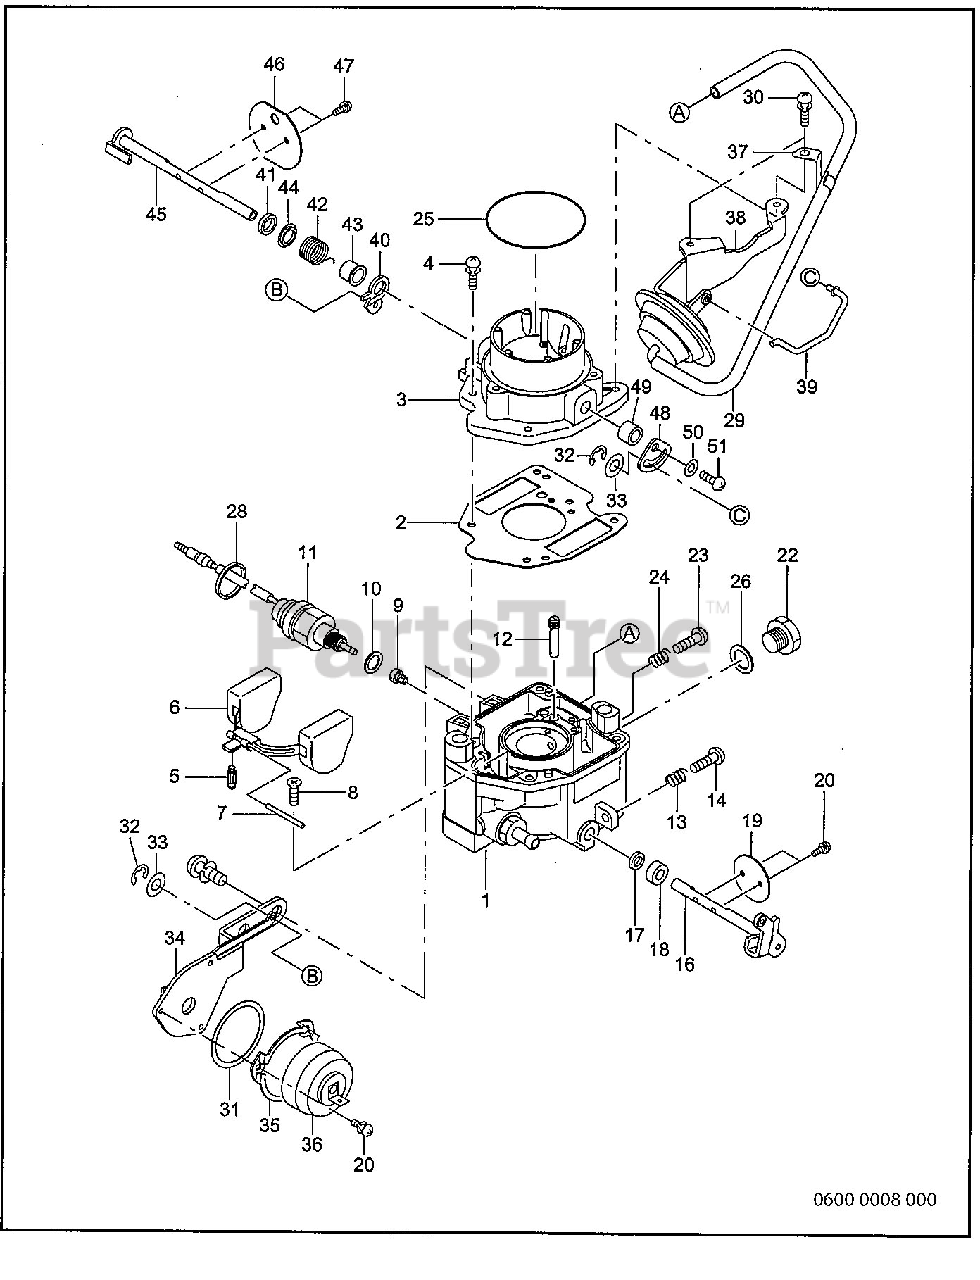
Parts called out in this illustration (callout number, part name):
1	CARBURETOR ASSY
2	GASKET, air horn
4	SCREW, air horn set
8	SCREW, float pin set
9	MAIN JET (#132)
11	SOLENOID VALVE ASSY
12	JET, slow (#60)
13	SPRING, adjust screw
14	SCREW, throttle adjust
16	THROTTLE SHAFT ASSY
17	FILTER, throttle shaft
18	COLLAR, THROTTLE SHAFT
19	THROTTLE VALVE
20	SCREW, valve set
25	O-RING, air horn
28	CLAMP, solenoid wire
30	SCREW, holder set
36	THERMOSTAT COVER ASSY
37	HOLDER, vacuum hose
38	CHOKE OPENER ASSY
39	ROD, choke piston
40	CHOKE LEVER ASSY
41	RING, choke lever
44	FILTER, choke shaft
45	SHAFT ASSY, choke
47	SCREW, valve set
